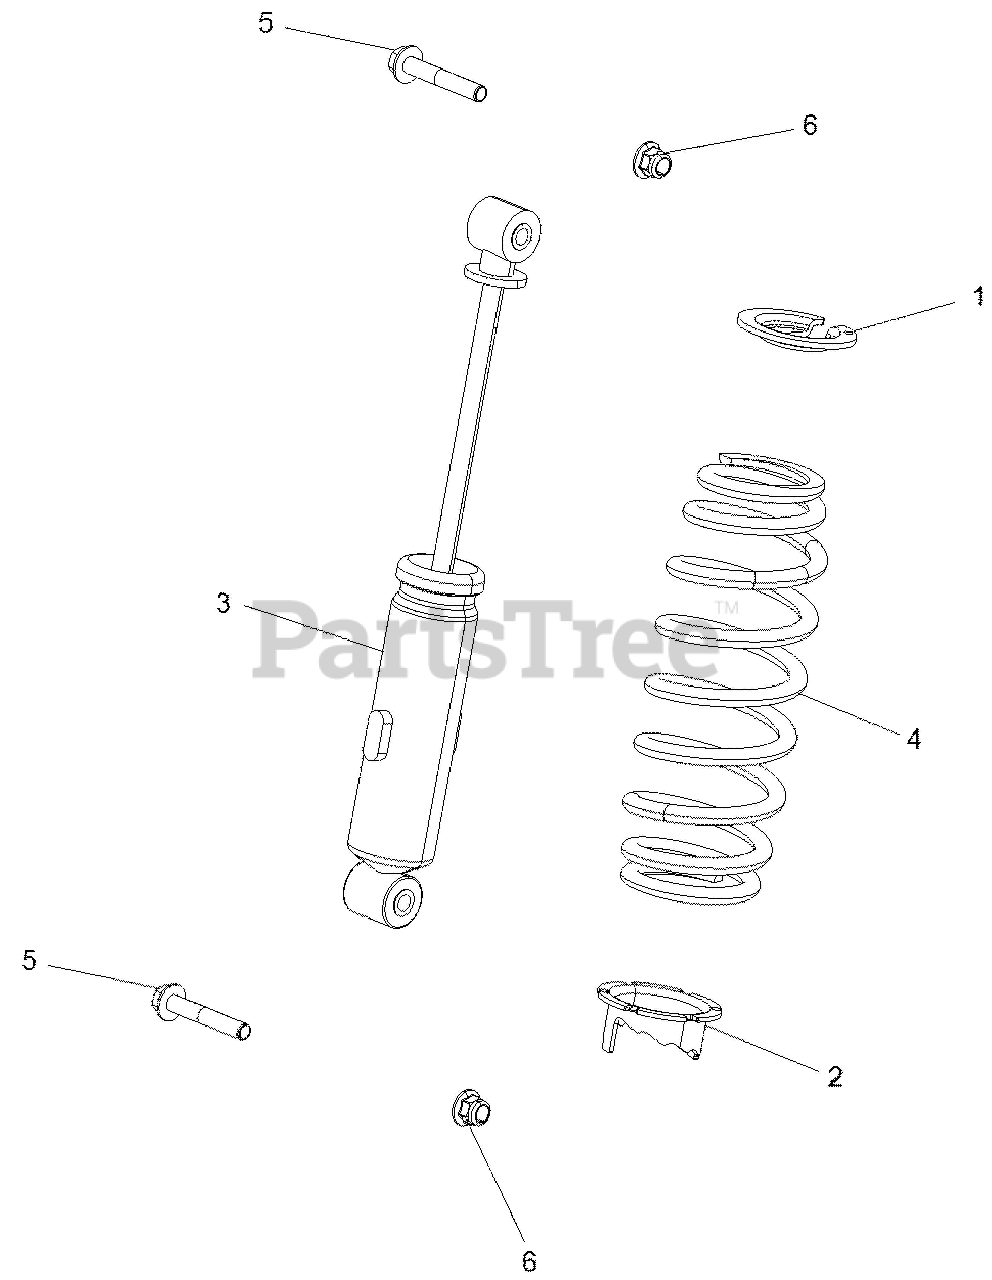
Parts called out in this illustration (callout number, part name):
1	RETAINER-SPRING,STEEL
2	CAM-ADJUSTING,SPRING,STEEL
3	SHOCK-FRONT,SPLY
4	SPRING-250#,M.BLK
5	SCR-HXFL-M10X1.25X60 10.9 ZOD
6	NUT-M10X1.25,FLG,NYLOC-OLIVE D
